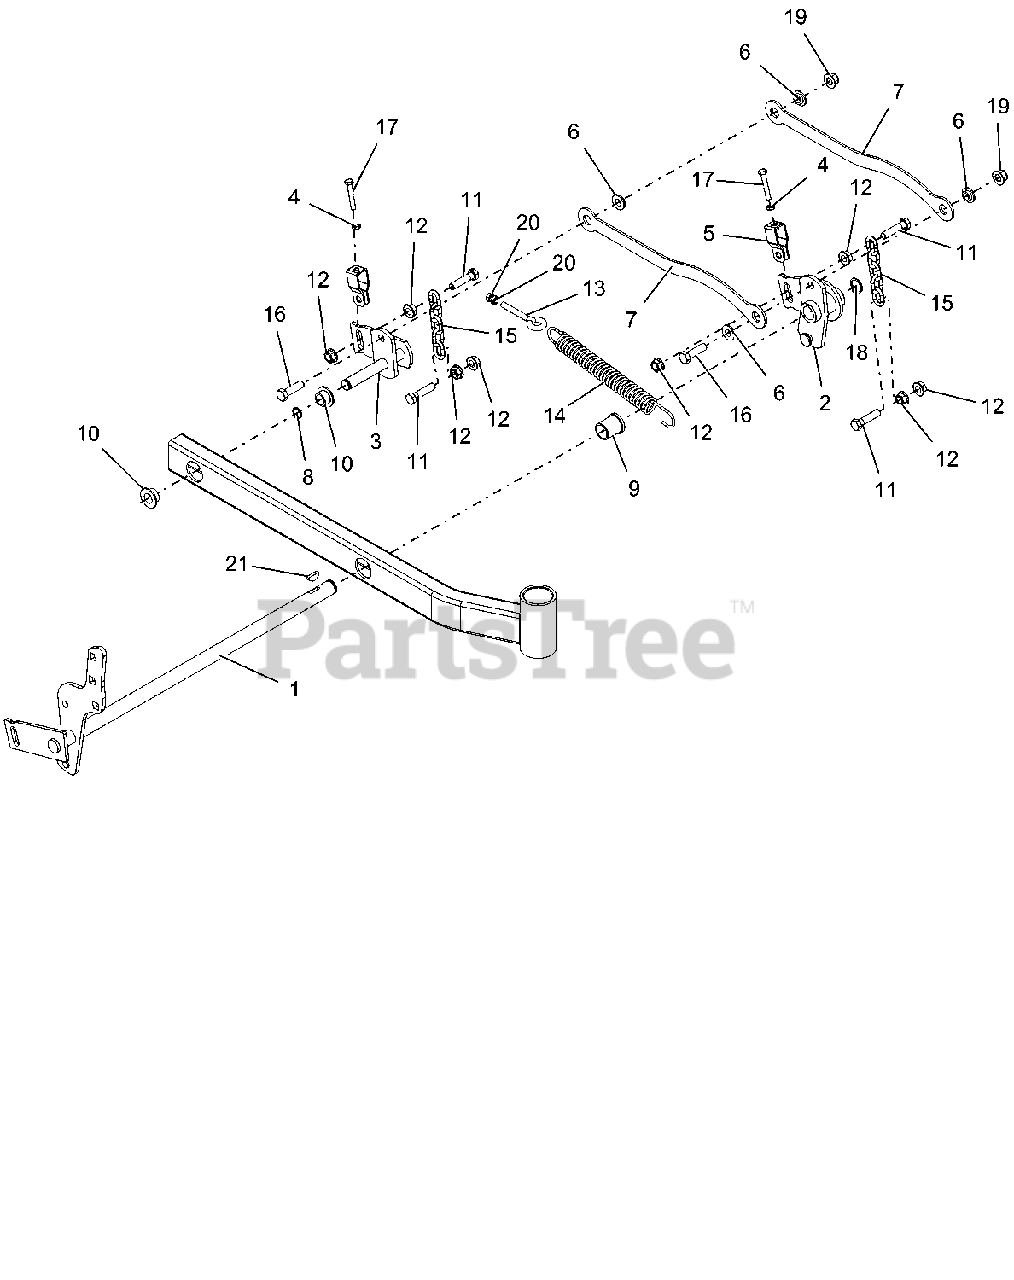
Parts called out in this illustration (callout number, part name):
1	WLDMT, FRONT RH DECK LIFT ARM
2	WLDMT, FRONT LH DECK LIFT ARM
3	WLDMT, REAR LH DECK LIFT ARM
4	NUT- JAM .312-18 YWZC
5	BRKT, DECK LEVELING
6	BSHG-FLG .515X.750X.395X1.120
7	LINK, DECK LIFT
8	RG-RTNG-EXT .689X.078
9	BSHG-FLG 1.00X1.25X1.50X1.50
10	BSHG-FLG .762X1.0X.580X1.48 NY
11	BLT, HEX M12-1.75X50 CLS8.8 YZ
12	NUT-SPNLK-FLG M12-1.75 YZ
13	BLT-EYE .375-16X2.50 YWZC
14	SG-TENS .162X1.25X8.25 WLD 25
15	CHAIN, LINK
16	@BLT-HEX .50-13X1.75 GR5 YWZC
17	BLT-HEX .312-18X2.00 FTH GR5YZ
18	RG-RTNG-EXT 1.00X.078
19	@NUT-LK-NYL-FLG .50-13 YWZC
20	NUT-HEX-JAM .375-16 YWZC
21	KEY-WDRF .25X1.00 HRD #15
